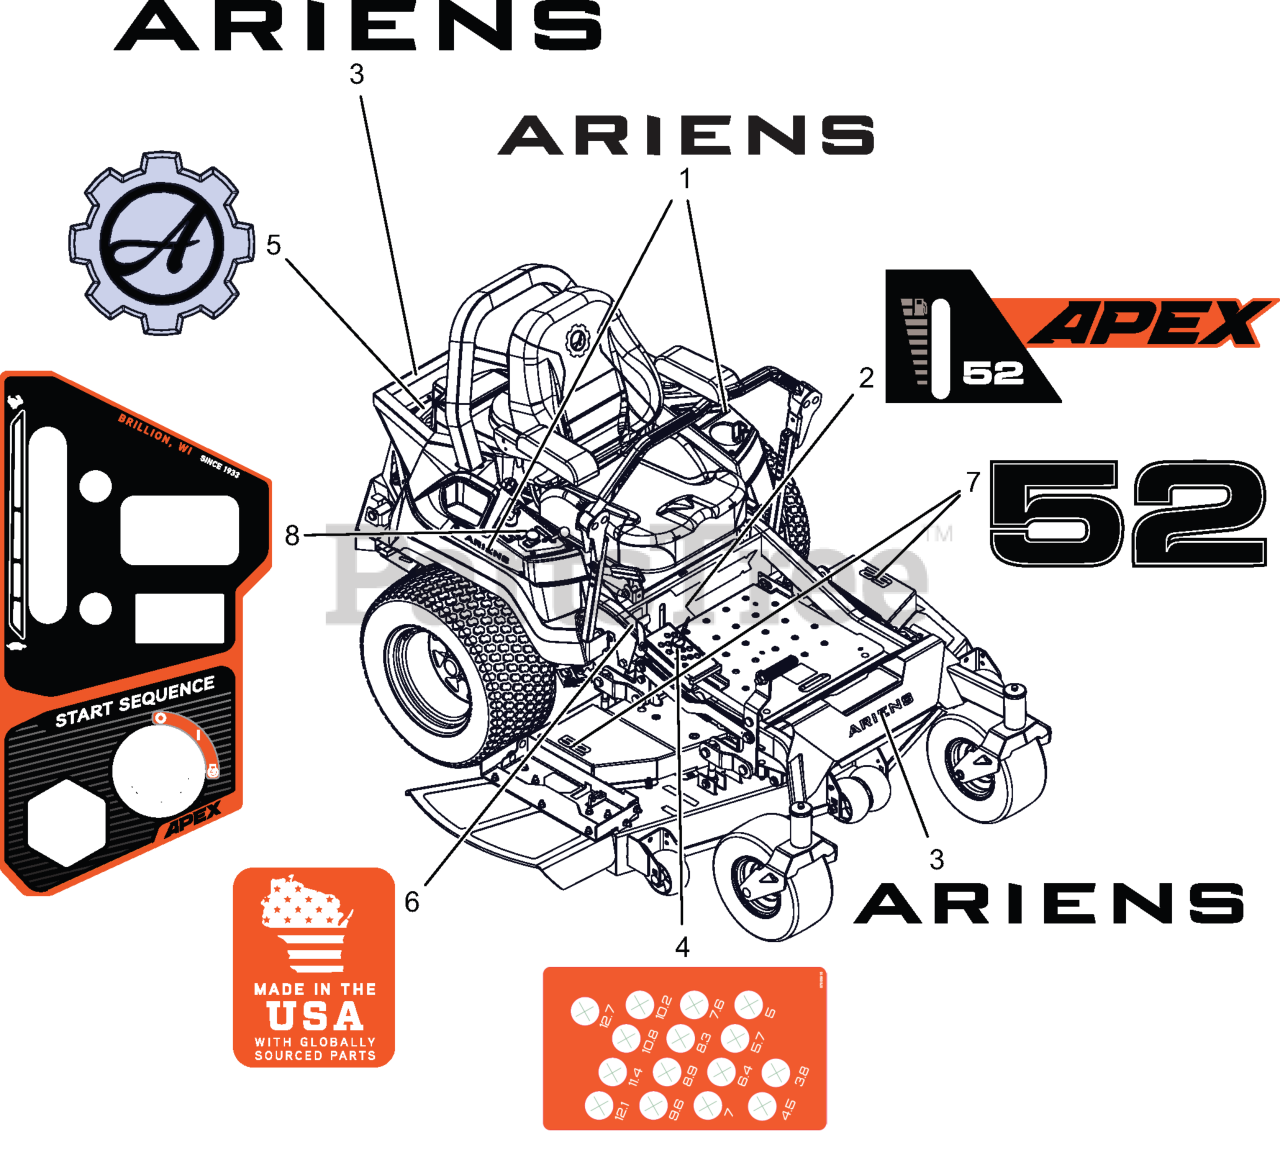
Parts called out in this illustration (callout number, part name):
1	DECAL- ARIENS 6.000" BLACK
2	DECAL- APEX 52 KICKPLATE
3	DECAL- ARIENS 9.625" BLACK
4	DECAL, APEX HOC METRIC
5	DECAL- ARIENS GEAR BADGE
6	DECAL- MADE IN USA
7	DECAL- DECK 52
8	DECAL- DASH -APEX & ZENITH
